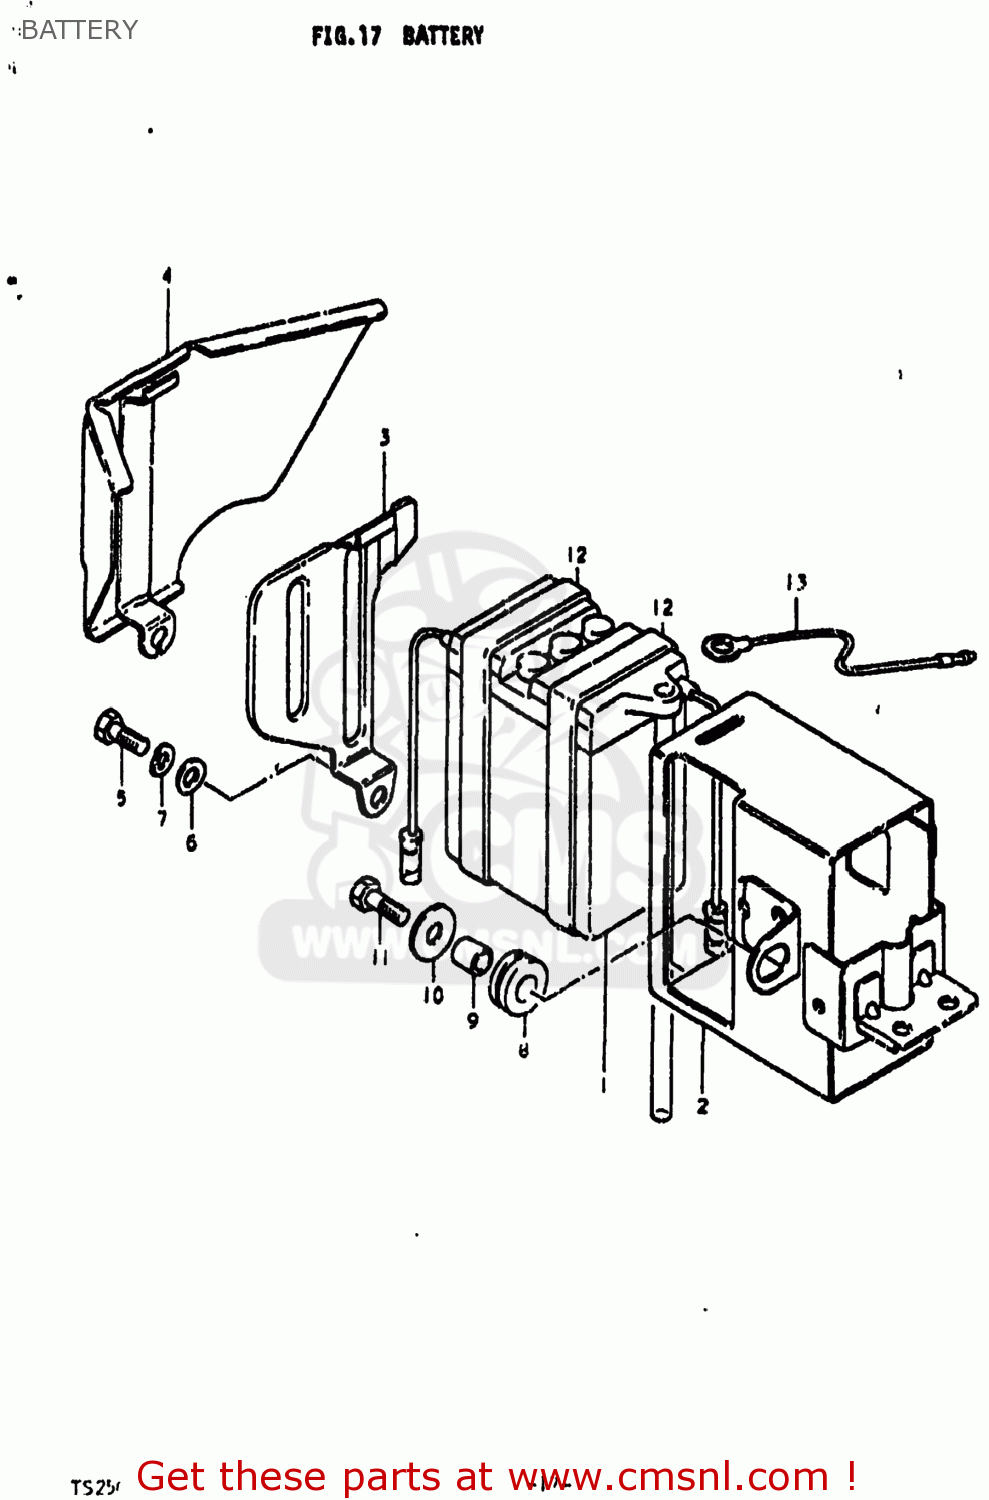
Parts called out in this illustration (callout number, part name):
1	BATTERY(6N4B-2A,6V4.2AH)
2	HOLDER,BATTERY
3	BRACKET,BATTERY HOLDER
4	COVER,BATTERY HOLDER
5	SCREW(6X10)
6	WASHER
7	LOCK WASHER
8	CUSHION
9	SPACER (7X9X7)
10	WASHER (6.5X20X1.2)
11	SCREW
12	PROTECTOR,BATTERY
13	LEAD WIRE
